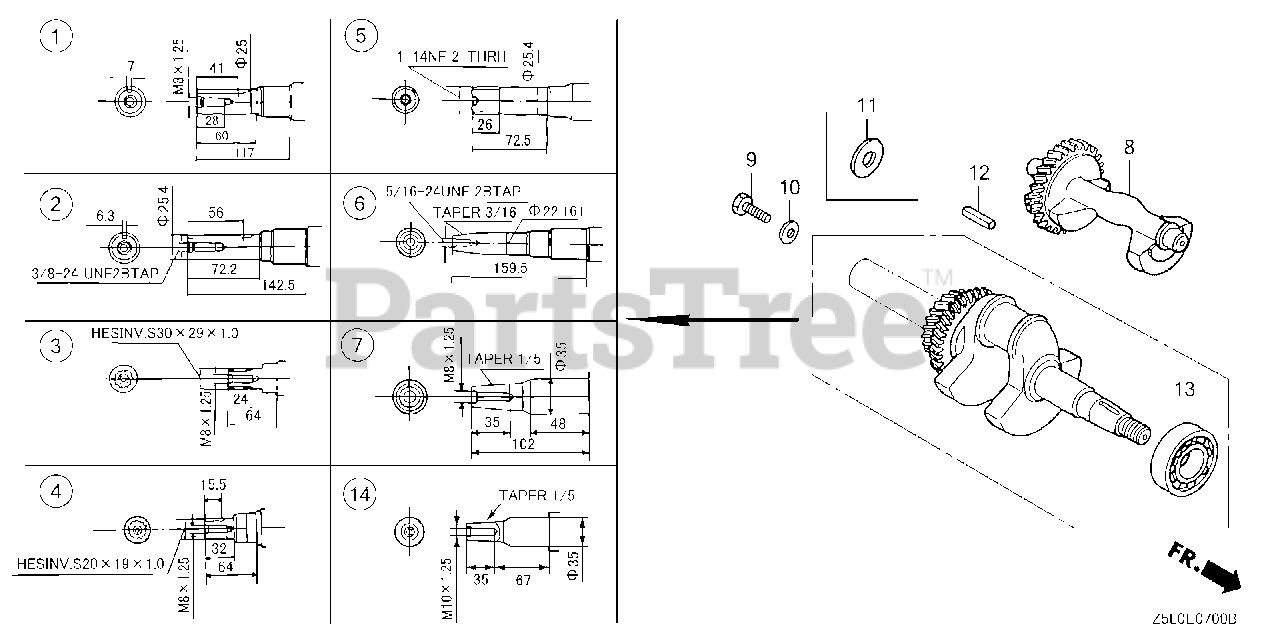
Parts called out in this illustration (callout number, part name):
1	CRANKSHAFT
8	WEIGHT, BALANCER
9	BOLT, HEX. (8X25)
11	WASHER, LOCK (8.5X35X4.5)
12	KEY (7X7X33) (OVER SIZE) (YELLOW)
13	BEARING, RADIAL BALL (6207SH)
